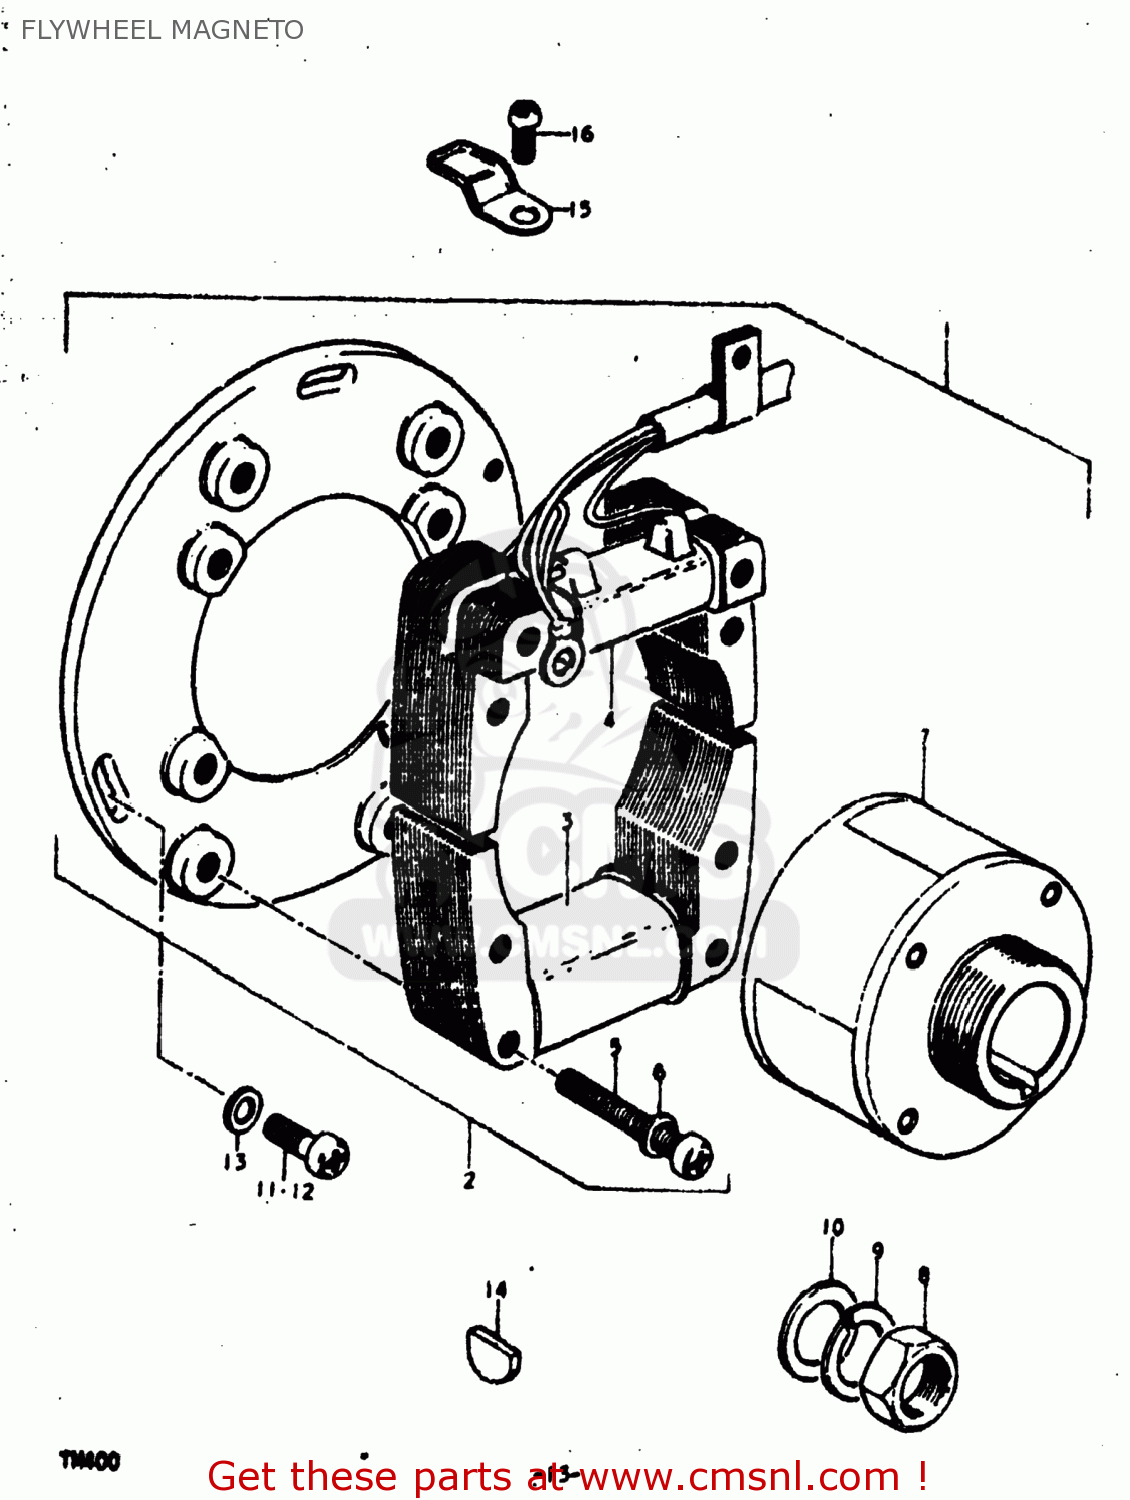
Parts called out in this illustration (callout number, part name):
1	MAGNETO ASSEMBLY
2	STATOR ASSEMBLY
3	COIL
4	COIL
5	SCREW 5X35
6	LOCK WASHER
7	ROTOR ASSEMBLY
8	NUT
9	LOCK WASHER
10	WASHER(14X27X3)
11	SCREW
12	SCREW(5X14)
13	WASHER
14	KEY 4MM
15	CLAMP
16	SCREW
